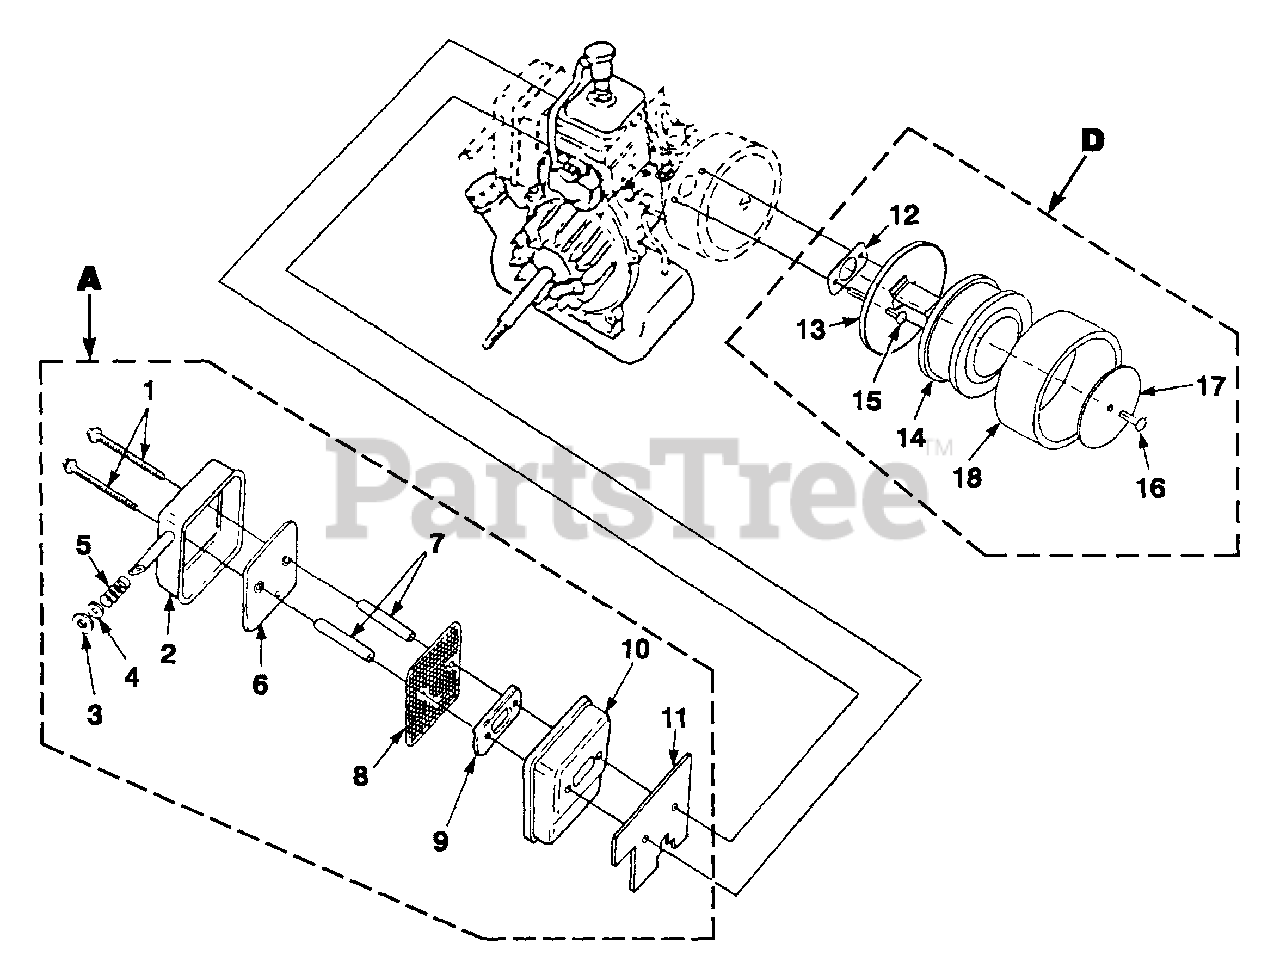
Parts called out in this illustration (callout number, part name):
1	Screw-Sems Hex Hd. (10-24 x 2 1/2")
2	Muffler Cover
3	Washer-Insulating
4	Washer-Flat
5	Compression Spring
6	Deflector
8	Spark Arrestor Screen
9	Reinforcing Plate
10	Muffler Body
11	Muffler Gasket
12	Carburetor Gasket
13	Plate-Filter
14	Air Filter
15	Screw-Sems Hex Hd. (10-24 x 2")
16	Screw-Machine (10-24 x 3/4")
17	Filter Washer
18	Pre-Filter
A	Complete Muffler
D	Air Filter Kit
